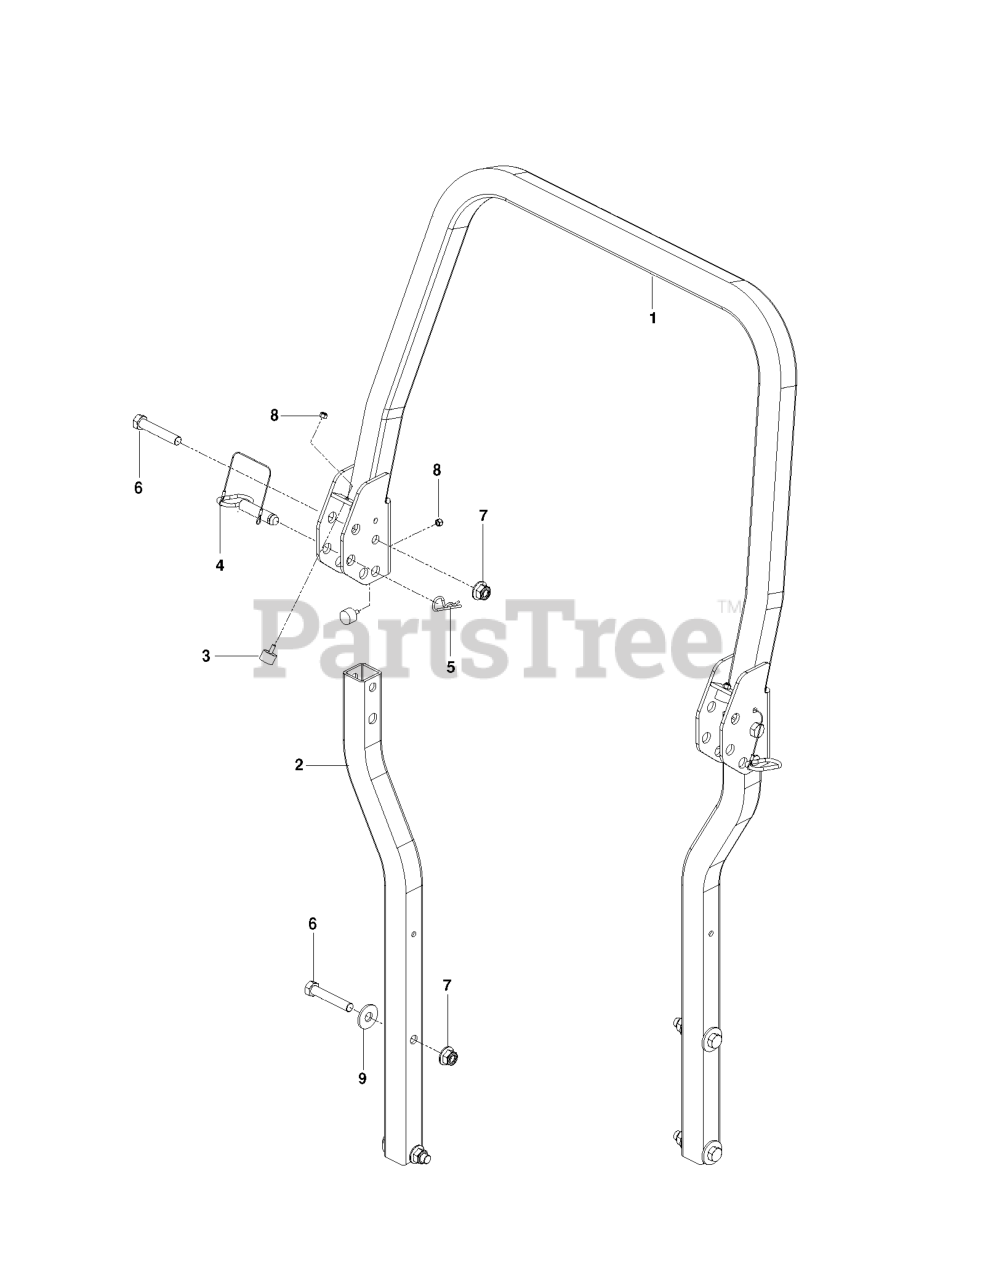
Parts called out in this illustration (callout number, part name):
1	ROPS.TOP.GRAY
2	TUBE.SIDE.ROPS.GREY
3	BUMPER, MALE STUD, 1/4-20
5	PIN HAIR .148 X 2-15/16 #210
6	5/8-11 X 3-1/2 HHB GRADE 5
7	NUT 5/8-11 FLG NYLOC ZD
8	NUT.1/4-20.HEX.NYLOC.ZD
9	WASHER, 5/8 FLAT
